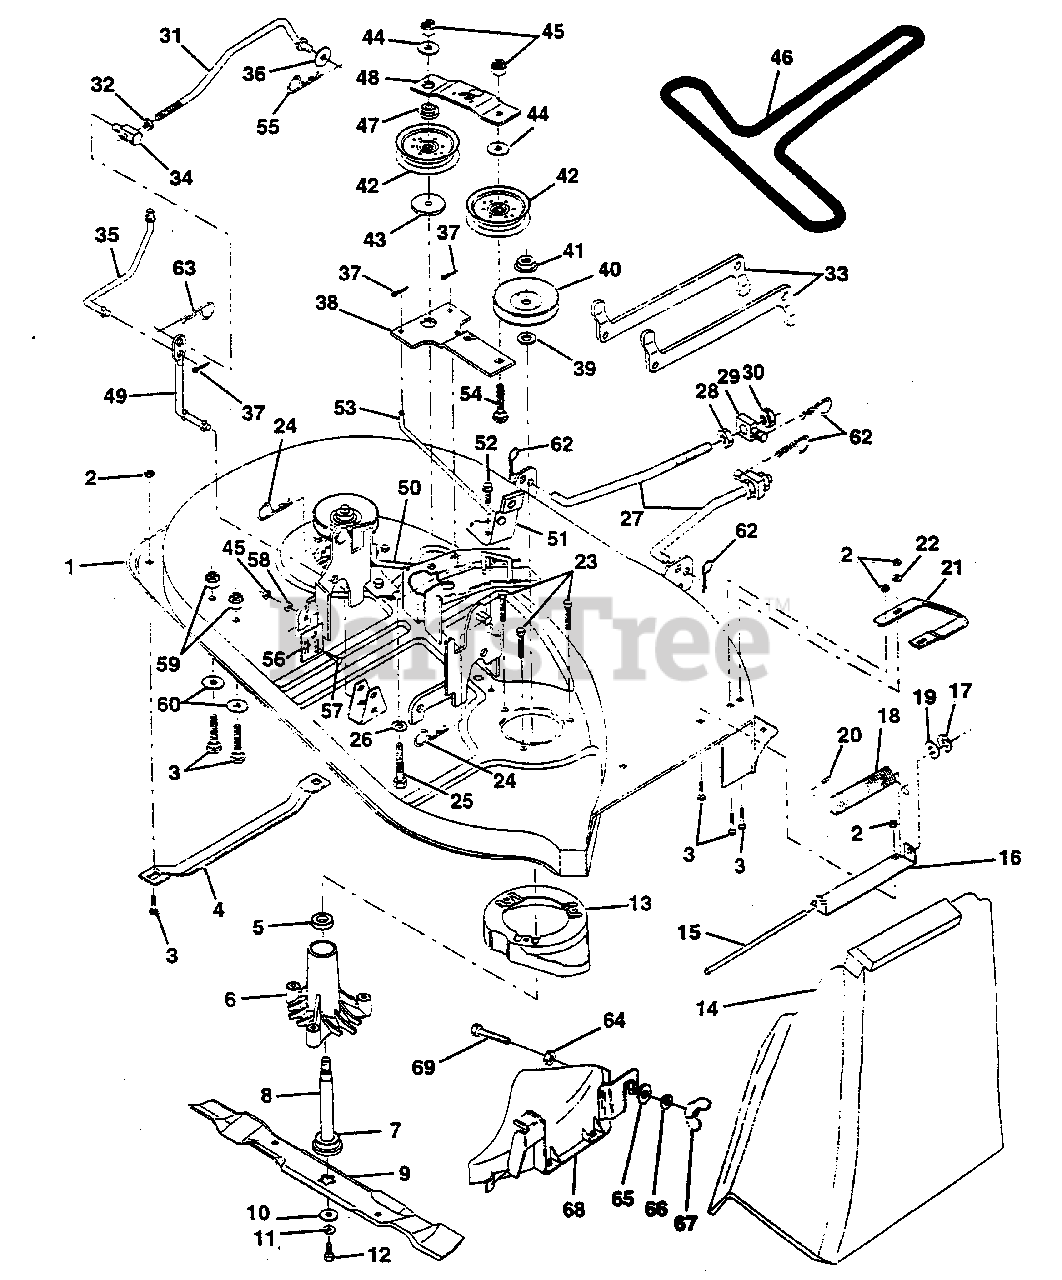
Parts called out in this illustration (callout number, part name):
1	Mower Housing
2	Nut, Crownlock 5/16-18
3	Bolt, Carriage 5/16-18 x 3/4
4	Runner, L.H.
6	Housing, Mandrel
7	Bearing
8	Shaft and Bearing Assembly, Mandrel (Inc. 7)
9	Blade, Mulching
10	Washer, Hardened
11	Washer, Lock 3/8
12	Bolt, Hex 3/8-24 x 1-1/4 Grade 8
13	Stripper, Mower, Vented
14	Shield, Deflector
16	Bracket Assembly, Deflector
18	Spring, Deflector
19	Washer 11/32 x 5/8 x 16 Gauge
22	Washer 11/32 x 3/4 x 16 Gauge
23	Bolt, Hex Head 5/16-18 x 1-1/4
24	Retainer, Spring
25	Bolt, Carriage 3/8-16 x 2-1/4
26	Washer 13/32 x 1 x 12 Gauge
27	Link Assembly, Front
28	Nut, Hex, Jam 1/2-13 UNC
29	Trunnion
30	Locknut with Washer Insert 1/2-13 UNC
31	Clutch Rod, Primary
32	Nut, Hex, Jam 3/8-16
33	Arm, Suspension, Rear
34	Trunnion 3/8-16
35	Clutch Rod, Secondary
36	Washer 13/32 x 13/16 x 16 Gauge
37	Pin, Cotter 3/32 x 3/4
39	Washer .150 Thick
40	Pulley, Mandrel
41	Nut, Flangelock 9/16
42	Pulley, Flat Idler
43	Spacer, Retainer
44	Washer 13/32 x 1 x 12 Gauge
45	Nut, Crownlock 3/8-16
46	Belt
47	Spacer, Idler Arm
48	Stiffener, Idler Arm
50	Rod, Brake, L.H.
51	Brake Assembly
52	Screw, Hex Washer Head, Thd., Roll. 5/16-18 x 3/4
53	Rod, Brake, R.H.
54	Bolt, Carriage 3/8-16 x 1-3/4 Grade 5
55	Spring, Retainer
56	Adjustment Plate, Rear Link
57	Bolt, Carriage 3/8-16
58	Washer 13/32 x 3/4 x 12 Gauge
59	Locknut, Hex, with Washer Insert 5/16-18
60	Washer 11/32 x 11/16 x 16 Gauge
62	Retainer, Spring
63	Retainer, Spring
64	Locknut 3/8-16
65	Washer 13/32 x 1-1/4 x 16 Gauge
66	Washer, Lock 3/8
68	Cover Assembly, Mulching
69	Bolt, Hex Head 3/8-16 x 1-1/4
